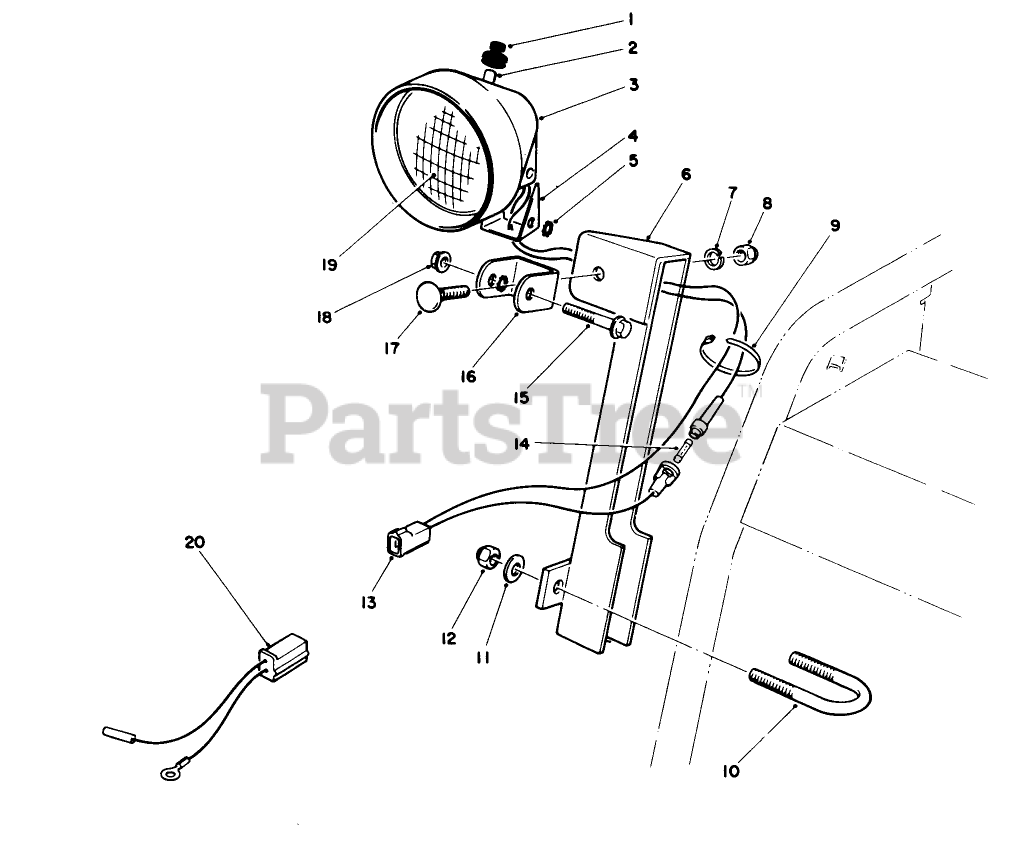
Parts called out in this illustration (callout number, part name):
1	BOOT-SWITCH
5	WASHER-LOCK
7	WASHER-LOCK
8	NUT-HEX
9	TIE-CABLE
10	U-BOLT
11	WASHER-PLAIN
12	NUT-LOCK, NI
13	WIRE ASM
14	Fuse-7-1/2 Amp.
15	SCREW-HH
17	BOLT-CARR
18	NUT-HF
20	WIRE ASM
